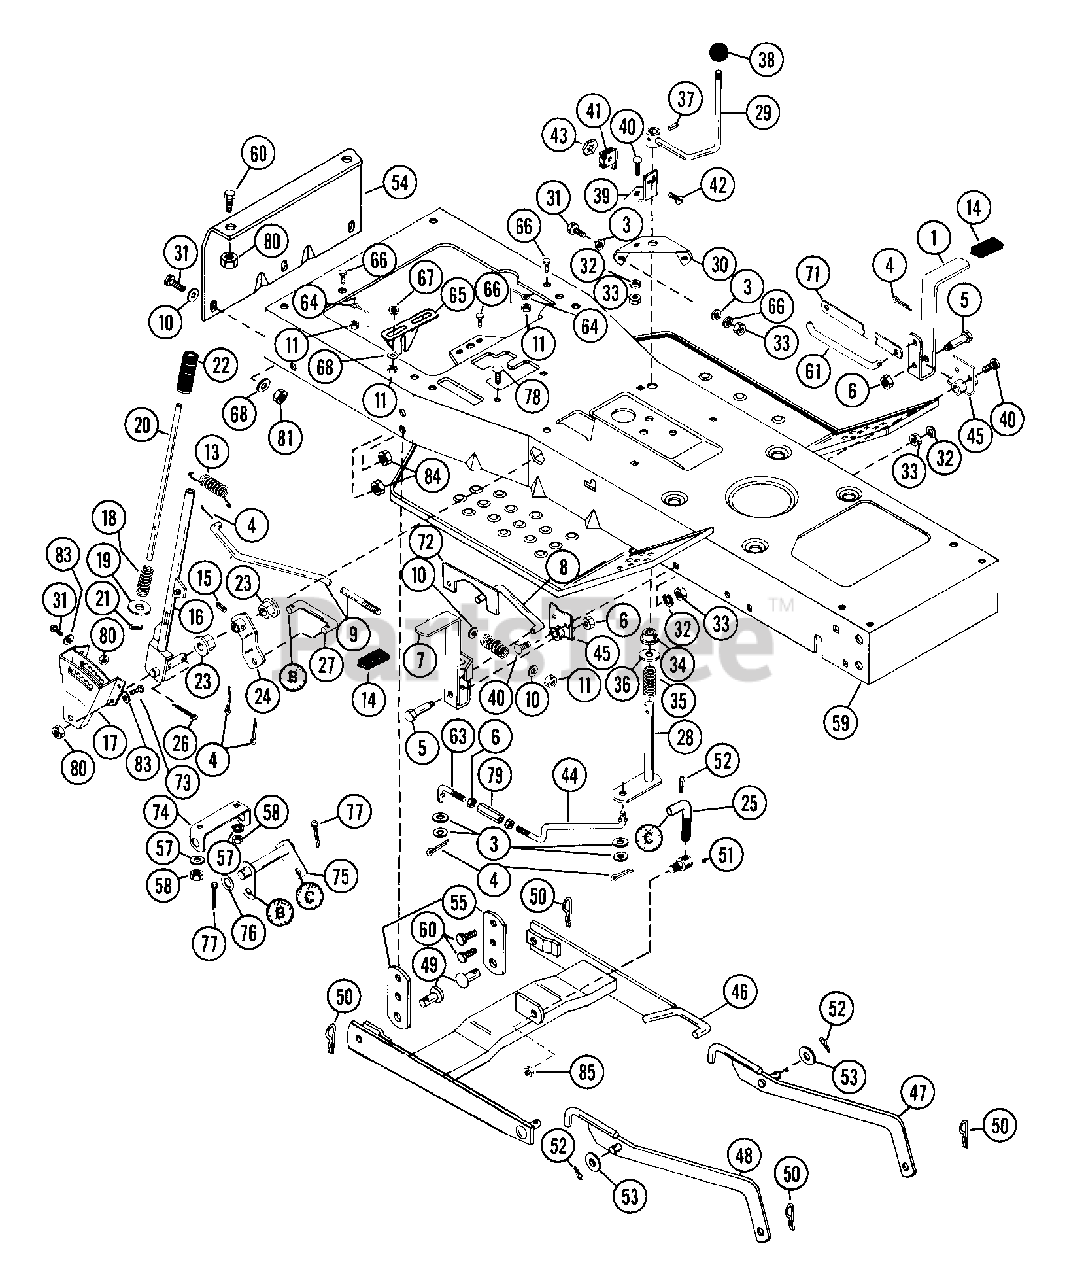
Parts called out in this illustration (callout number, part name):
1	CLUTCH PEDAL
2	NUT-LK-CTR .625-18 PL
3	WSHR-FL-STL.406X.812X.065PL
4	PIN-COTR .12X1.0 PL
5	SHOULDER BOLT .50 X 1.75
6	NUT-LK-JAM-CTR .375-16 PL
7	BRAKE PEDAL
8	PARKING BRAKE ROD
9	BRAKE ROD
10	WSHR-FL-STL .38X.875X.083 PL
11	NUT-LK .312-18 GR A PL
12	SG-COMP .102X.85X1.031
13	SG-TENS .072X.75X2.81 WLD ??
14	PEDAL COVER
15	PIN-GRV .250X1.25 TP A
16	LIFT HANDLE
17	LIFT QUADRANT
18	SG-COMP .048X.59X2.06 WLD9
19	WSHR-FL-STL .458X.750X.06 PL
20	PLUNGER ROD
21	PIN-GRV .250X1.25 TP A
23	FLANGE BUSHING
24	LIFT ARM
25	ADJUSTMENT LINK
26	PIN-COTR .12X1.50 PL
27	LIFT LINK
28	PTO LEVER
29	P T O HANDLE
30	BRACKET
31	BLT-HEX .31-18X.75 PL GR5
32	WSHR-LK .312X.097 PL HVY
33	NUT-HEX .312-18
34	BSHG-FLG.500X.625X.312X.750NY
35	SG-COMP .080X.85X1.44
36	WSHR-FL-STL .531X1.062X.095 PL
37	PIN-ROLL .188X1.25
38	SHIFT BALL
39	SWITCH BRACKET
40	BLT-RDHDSQNK .31-18X.75 GR5 PL
41	SWITCH INTERLOCK
42	SCR-MCH 10-24X1.00 SLRH PL
43	NUT-KEPS 10-24 PL
44	IDLER LINK
45	PEDAL PIVOT
46	REAR HANGER
47	RIGHT HANGER
48	LEFT HANGER
49	PIN-CLEV .494X1.25 YWZC
50	PIN-HAIR INT .09X.188 PL
51	ROD END
52	PIN-HAIR INT .08X.38X1.42 YWZC
53	WSHR-FL-STL .531X1.062X.095 PL
54	DRAW BAR
55	HANGER BRACKET
57	WSHR-LK .375X.094 MED PL
58	NUT-HEX .375-16
59	FRAME W/DECALS
60	BLT-HEX .38-16X.75 PL GR5
61	CLUTCH ROD
63	IDLER ADJUSTOR LINK
64	BELT FINGER
65	CAM ACTUATOR
66	BLT-HEX .31-18X.88 PL GR2
67	SPACER -FLANGED .325X.498X.318
68	WSHR-FL-STL.312X.734X.065PL
73	BLT-HEX .31-18X1.25 PL GR5
74	CENTER LIFT BRACKET
75	CENTER LIFT LEVER
76	WSHR-FL-STL .754X1.125X.062 PL
77	PIN-COTR .12X1.50 PL
78	BLT-RDHDSQNK .38-16X.75 SHT PL
79	NUT-CUPLG .375-16 PL
80	NUT-LK-TOP .312-18 GR C PL
81	NUT-JAM .50-13 PL
83	WSHR-FL-STL.312X.734X.065PL
84	NUT-LK TOP .375-16 GR C YWZC
85	NUT-LK-CTR .50-13
